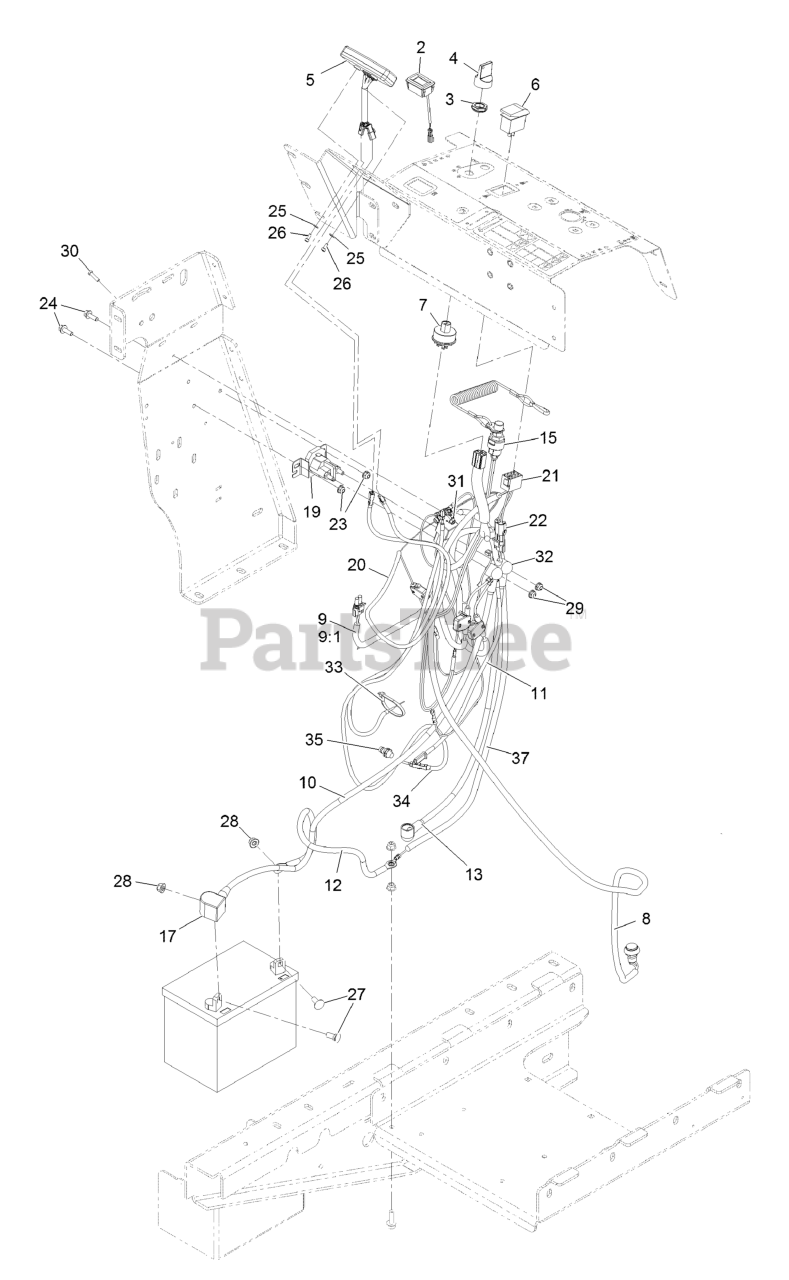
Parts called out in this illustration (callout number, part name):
2	METER-TACH/HOUR
3	NUT-SWITCH, KEY
4	KEYS-IGNITION (SPARE PAIR
4	KEY-UMBRELLA
5	HEAD ONLY, STRIKER
6	SWITCH-ROCKER
7	SWITCH-IGNITION
8	Switch-Push Button
9	Harness, Main
9:1	RELAY-MINI ISO PWR, 5M
10	CABLE-POSITIVE
11	Wire-Solenoid
12	CABLE-GROUND
13	CABLE-POSITIVE
15	SWITCH-OP
17	Insulator-Battery
19	Solenoid-Starter
20	HARNESS-STRIKER
21	CONNECTOR-CARLING, 8F
22	Connector-Wp,2M
23	Nut-Hex Flange
24	Screw-HHF
25	WASHER-FLAT
26	SCREW-HSH
27	SCREW-CARR
28	Nut-Hex Flange
30	SCREW-HH
31	Nut-Hex Flange
32	INSULATOR-SOLENOID
33	TIE-CABLE
34	Cable-Trail Tech, Sensor
35	MAGNET, SPEEDOMETER
37	HARNESS-WIRE, JUMPER
